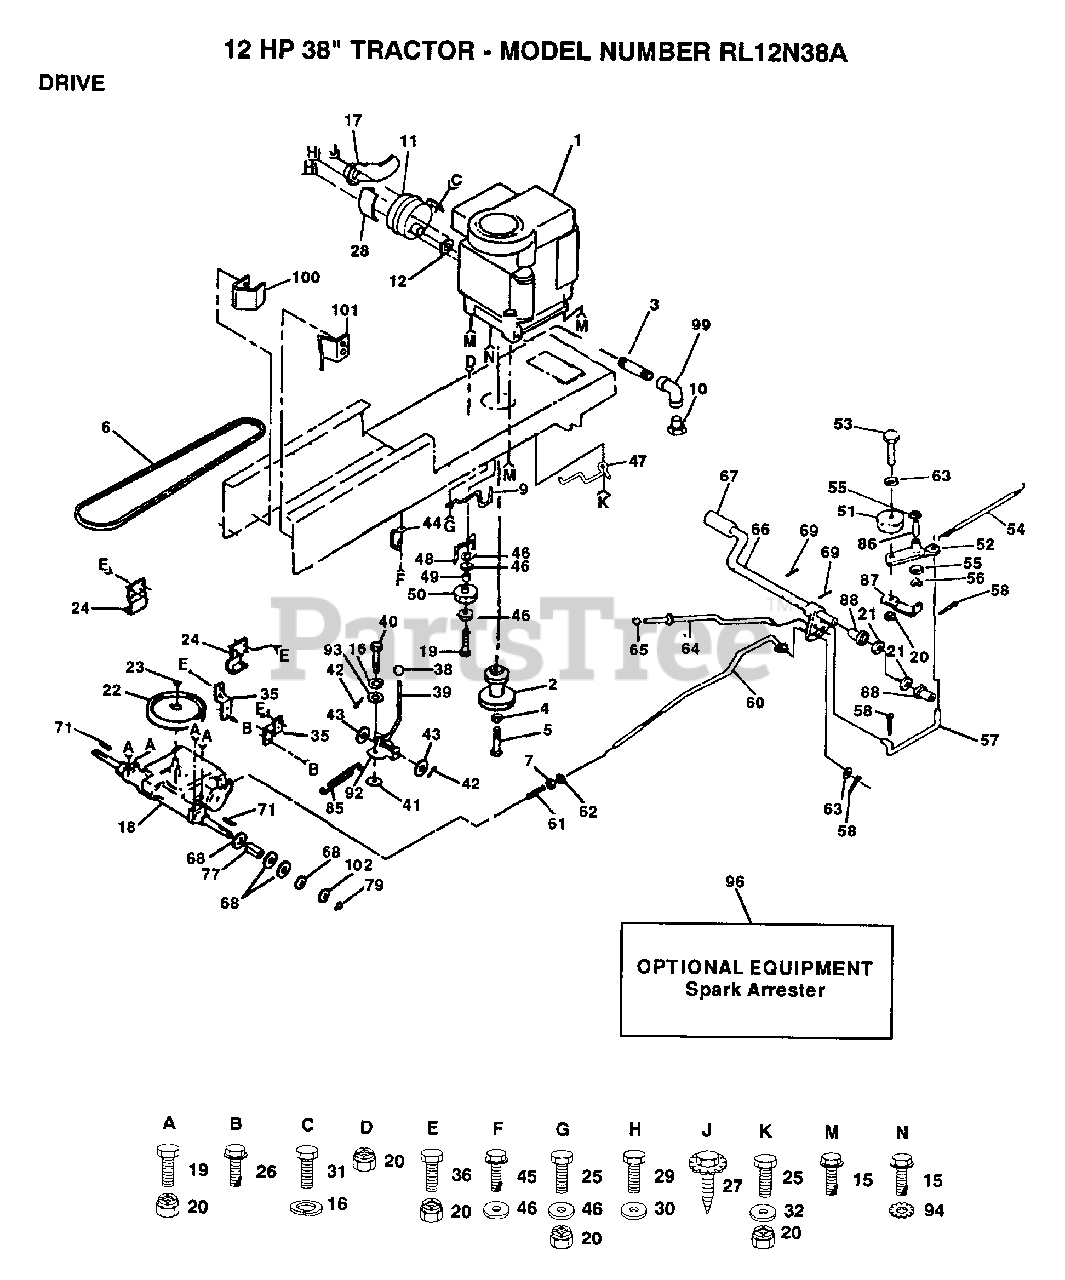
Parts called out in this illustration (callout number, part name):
3	PIPE NIPPLE
4	LOCKWASHER
5	BOLT
6	BELT-V.90.0.GD.DR
7	NUT
9	KEEPER.BELT.ENG.L
11	MUFFLER LTV
15	SCREW
16	LOCKWASHER
17	DEFLECTOR MUFFLER
19	BOLT
21	WASHER LT
22	PULLEY TRANS
24	BRACKET LT
25	BOLT
26	SCREW
28	SHIELD HEAT LTV
29	"BOLT,HEX"
30	WASHER T
31	BOLT
32	WASHER
35	STRAP TORQUE
38	CONTROL KNOB LT
39	ROD SHIFTER
41	WASH-SHFT PLT LT
42	PIN COTTER 1/8
43	WASHER
45	SCREW
46	WASHER
47	KEEPER BELT ENG
48	BELT KEEPER LT
49	SPACER T
50	PULLEY.IDLER.FLAT
52	ARM IDLER
54	"SPRING, RETURN LT"
55	WASHER LT
56	KLIP RING
57	"LINK, CLUTCH T"
58	COTTER PIN
61	SPRING ROD LT
62	NUT
63	WASHER
64	PARKING BRAKE ROD
67	PEDAL COVER T
68	WASHER
71	SQUARE KEY
77	SPACER LT
79	E-RING LT
86	"LY, BEARING"
87	RETAIN BELT
88	NYLON BEARING
92	PLATE SHIFT LT
93	WASHER LT
94	LOCKWASHER
99	ELBOW
100	"KEEPER,BELT LH T"
101	"KEEPER,BELT RH T"
102	WASHER
